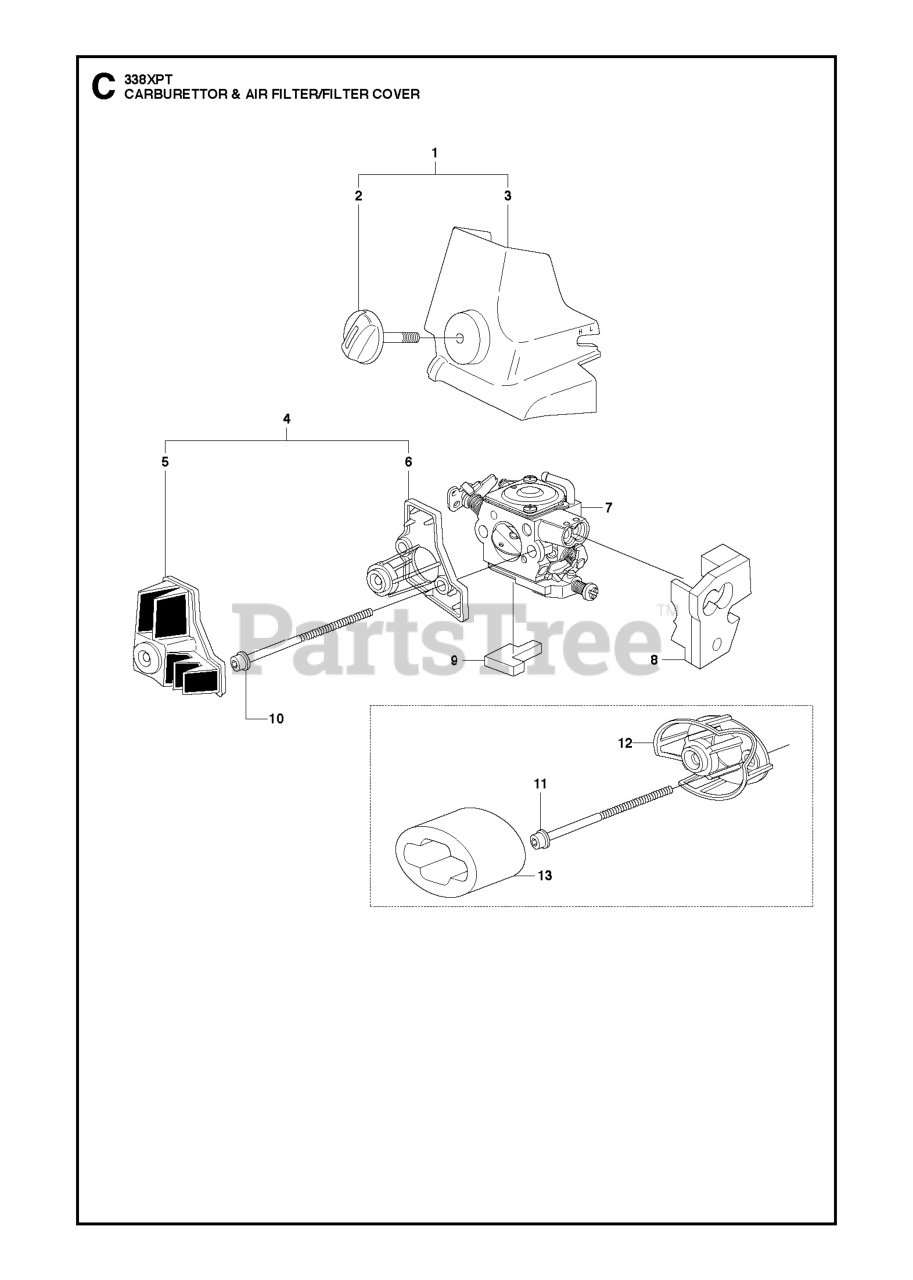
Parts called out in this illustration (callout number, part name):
4	AIR FILTER KIT
4	AIR FILTER
5	AIR FILTER
6	FILTER HOLDER
7	CARBURETOR
13	AIR FILTER
